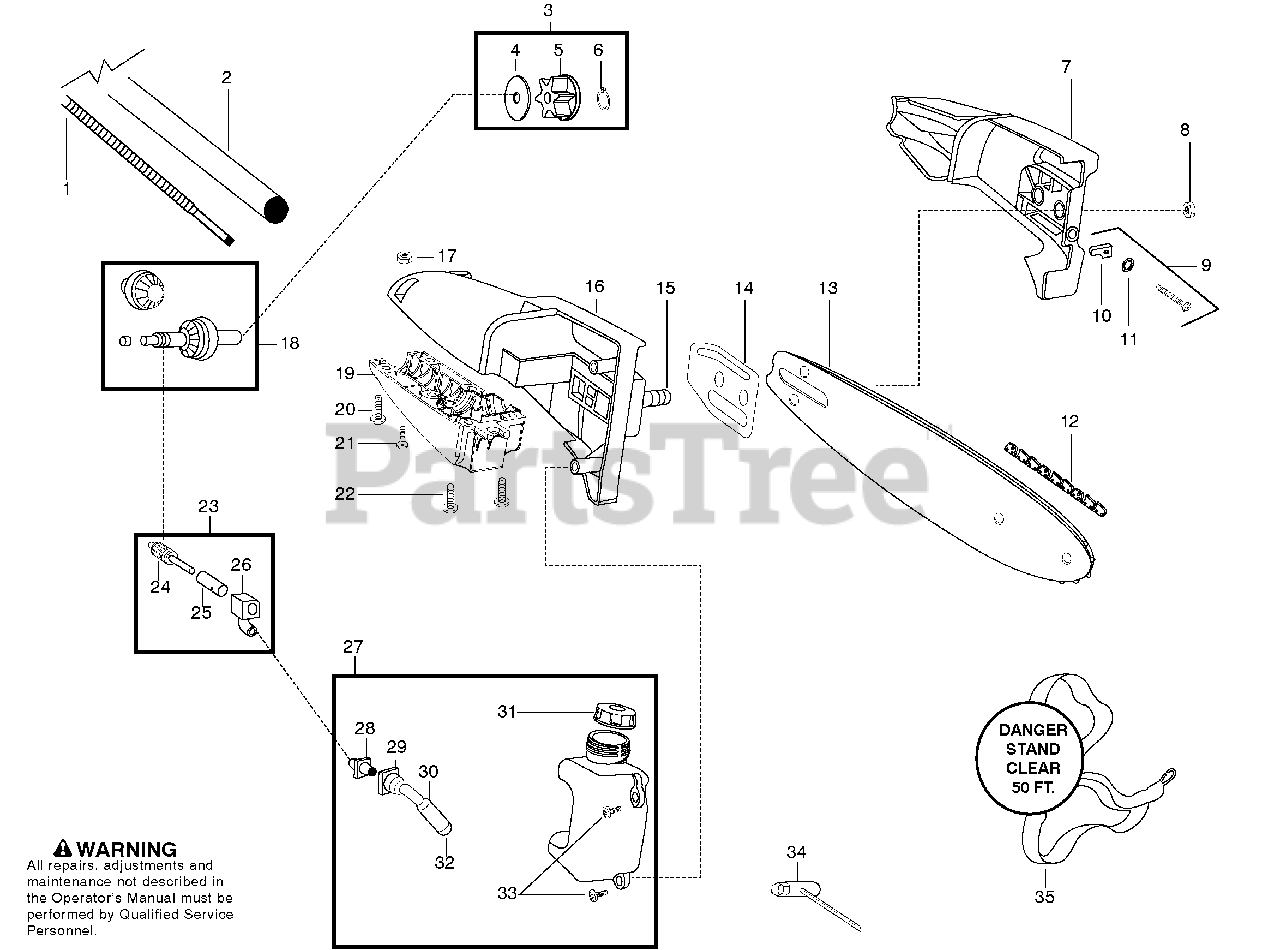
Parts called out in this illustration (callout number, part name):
1	Flexshaft - lower
2	Assy. - Lower Driveshaft
3	Kit - Sprocket Assy.
6	Retainer - Sprocket
7	Assy - Bar Clamp
8	Nut - Bar Mounting
9	Kit - Bar Adjust
10	Pin - Bar Adjust
11	Retainer - Bar Adjust
12	Chain - 8"
14	Plate - Bar Pad
16	Housing - Upper
18	Kit - Gear Assy.
19	Housing - Lower
21	Screw - Alignment
23	Kit - Oil Assy
24	Assy. - Gear Plunger
26	Assy- Oil Block
27	Assy - Oil Tank
28	Fitting - Oil Line
29	Intake - Oil Line
30	Filter - Oil
31	Cap - Oil
32	Plug - Oil Filter
35	Strap-Shoulder
